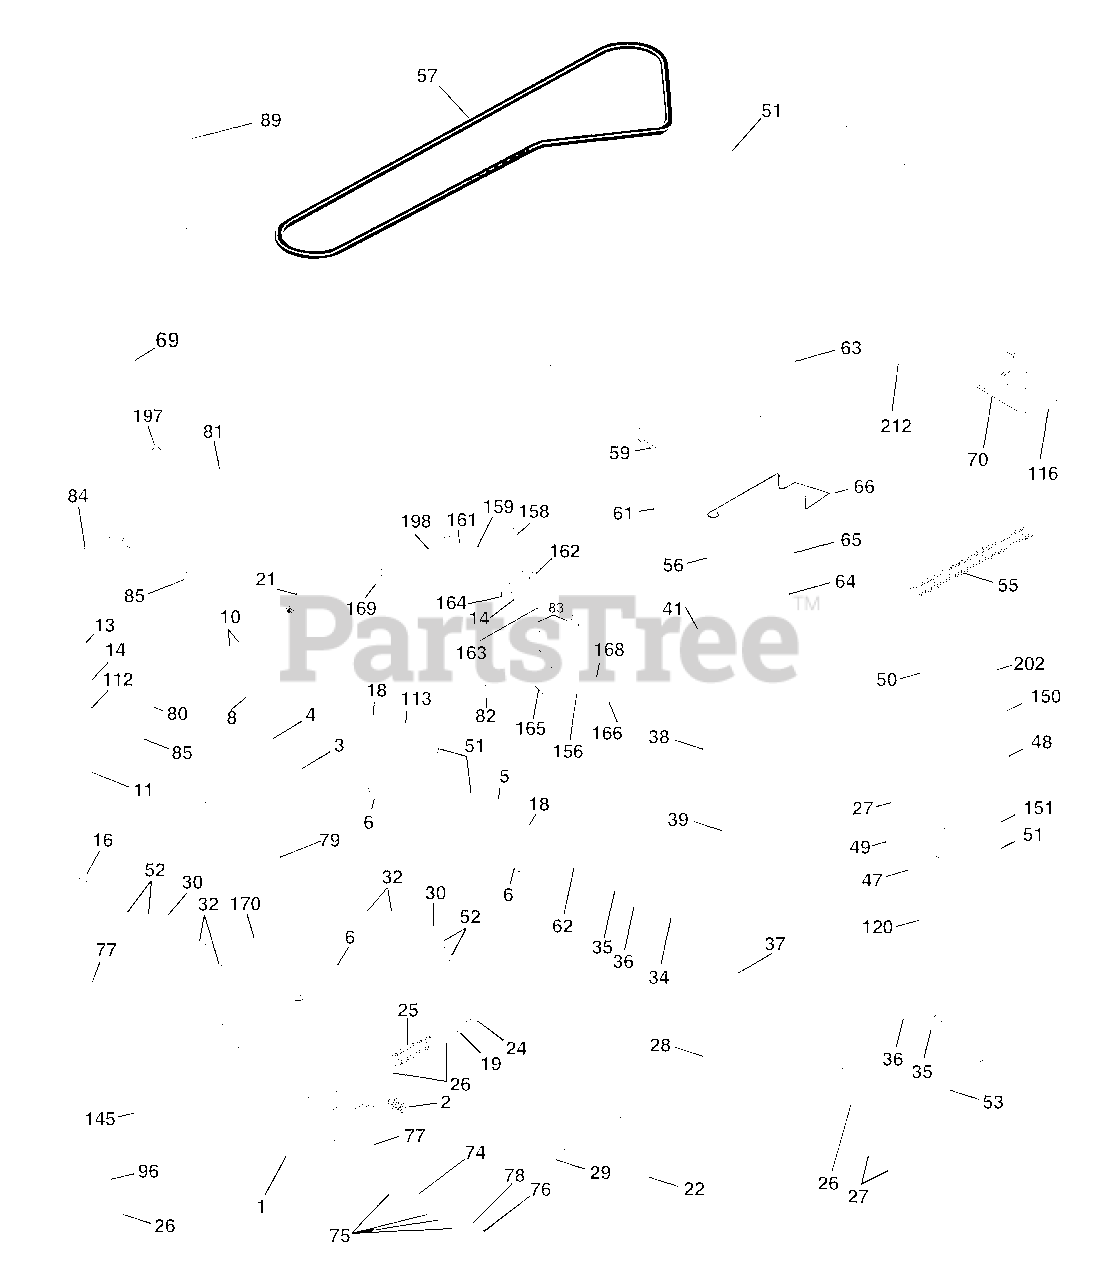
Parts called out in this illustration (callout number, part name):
2	Spring Return Brake T/a Zinc
3	Pulley Transaxle 18" tires
4	Ring Retainer # 5100-62
5	Strap Torque 30 Degrees
6	Screw 5/16-18 X 3/4
8	Rod Shifter Fender Adj Lt
10	Pin Cotter 1/8 X 1 Cad
11	Washer Plate Shf 388 Sq Hole
13	Bolt 1/4-28 Unf Gr 8 W/Patch
14	Washer Lock Hvy Helical 1/4
16	Nut Lock Hx W/Ins 5/16-18 Unc
18	Bolt, Fin Hex 3/8-16 UNC x 1 Gr. 5
19	Nut Lock 3/8-16 Unc
21	Knob
22	Rod Brake Blk Zinc 26 840
24	Nut Hex Jam 3/8-16 Unc
25	Spring Rod Brake 2 00 Zinc
26	Washer 13/32 X 13/16 X 16 Ga
27	Pin Cotter 1/8 X 3/4 Cad
28	Rod Brake Parking LT/YT
29	Cap Brake Parking
30	Bracket Mtg Transaxle
32	Bolt Hex Hd 5/16-18unc X 3/4
34	Shaft Asm Pedal Foot
35	Bearing Nylon Blk 629 Id
36	Washer 21/32 X 1 X 16 Ga
37	Pin Roll 3/16 X 1"
38	Pulley Idler Composite
39	Bolt Fin Hex 3/8-16 X 3
41	Keeper Belt Idler
47	Pulley Idler V Groove Plastic
48	Bellcrank Asm
49	Retainer Belt Style Spring
50	Bolt Carr Sh 3/8-16 x 1-1/2 Gr.5
51	Nut Crownlock 3/8-16 Unc
52	Nut Crownlock 5/16-18 Unc
53	Link Clutch
55	Spring Return Clutch 6 75
56	Screw 3/8-16 X 1-1/4
57	V-Belt Ground Drive
59	Keeper Belt Span Ctr
61	Screw 3/8-16 x .875
62	Cover Pedal Blk Round
63	Engine Pulley LT/YT
64	Bolt Hex
65	Washer Lock Hvy Hlcl Spr 7/16
66	Keeper Belt Engine Foolproof
69	Screw Hex Wsh Hi-Lo 1/4-1/2 Unc
70	Guide Belt Mower Drive RH
74	Spacer Axle
75	Washer 25/32 X 1 1/4 X 16 Ga
76	E-ring #5133-75
77	Key Square 2 0 X 1845/ 1865
78	Washer 25/32 X 1-5/8 X 16 Ga
79	Key Woodruff
80	Arm Shift
81	Shaft Asm Cross Tapered 20"t
82	Spring Torsion T/a
83	Washer 17/32 X 3/4 X 16 Ga
84	Link Transaxle
85	Nut Lock Center 1/4 - 28 FNTHD
89	Console Shift STLT
96	Retainer Spring
112	Washer 9/32 x 3/4 x 10 Ga.
113	Strap Torque Lh
116	Bolt Rdhd Sq Neck 3/8-16 x 1
120	Nut Lock Flg 3/8-16
145	Bolt Hex 5/16-18 Gr. 5
150	Spacer Retainer
151	Washer 13/32 x 2 x 10
156	Washer Srrted 5/16 ID x 1.125
158	Bracket Shift Mount
159	Hub Tapered Flange Shift lt
161	Bolt Rdhd Sqnk 1/4-20 x 3/4 Gr 5
162	Nut Crownlock 1/4-20 Unc
163	Bolt Hex Fin 1/4-20 Unc x 1 Gr 5
164	Washer 5/8 x .281 x 10 Ga
165	Bracket Pivot Lever
166	Screw 5/16-18 x 5/8
168	Bolt Shoulder 5/16-18 x .561
169	Plate Fastening Lt
170	Keeper Belt Transaxle
197	Nyliner Snap-In
198	Washer Nyliner
202	Bolt Carr. Sh 3/8-16 x 1-3/4 Gr. 5
212	Nut Hex Flange Lock
